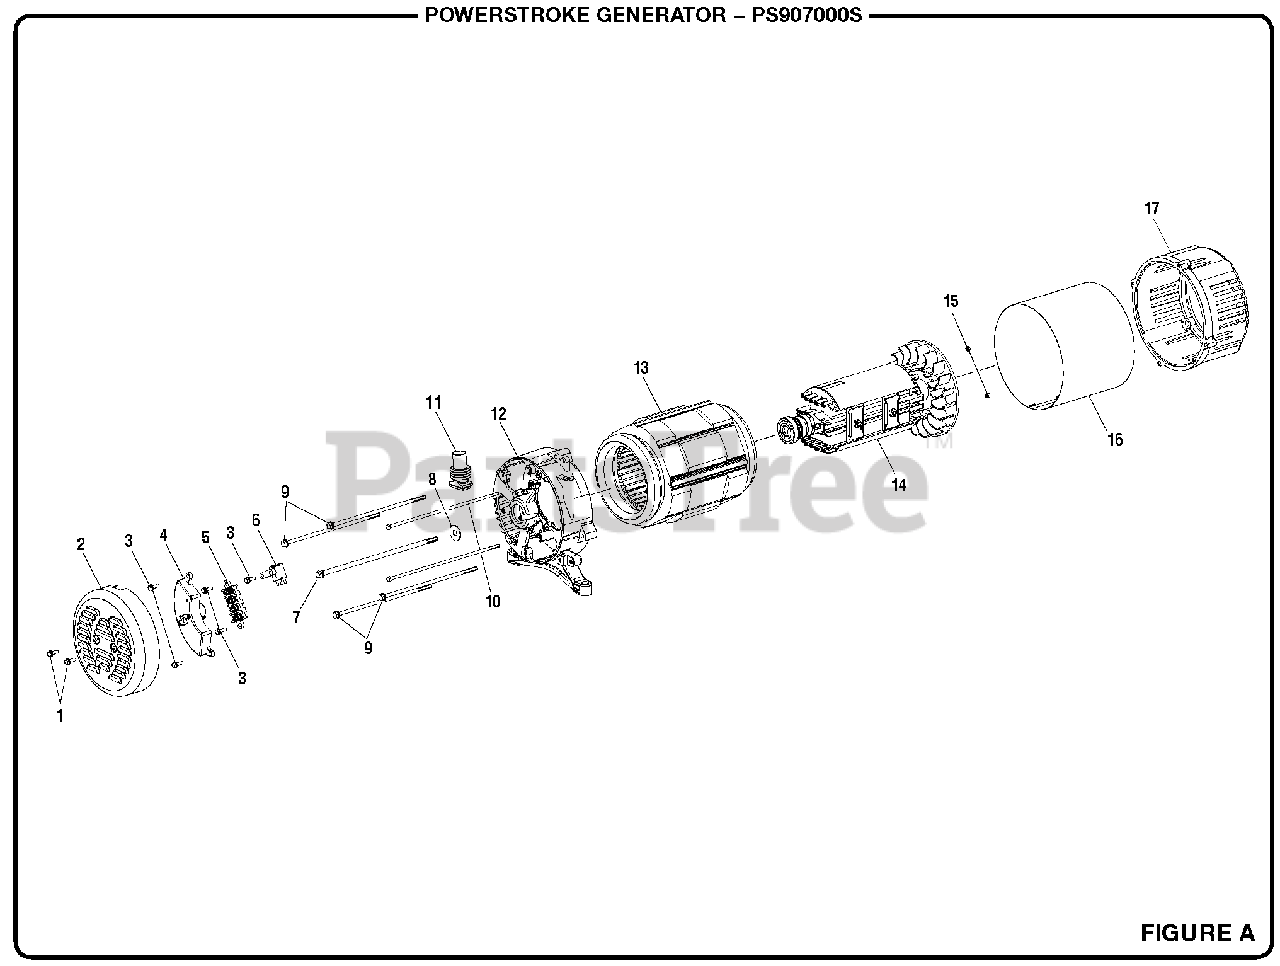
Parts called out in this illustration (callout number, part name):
1	Bolt (M5 x 12 mm, Hex Flange Hd.)
2	Brush Cover
3	Bolt (M5 x 16 mm, Hex Flange Hd.)
4	Automatic Voltage Regulator
5	Terminal Block
6	Brush Assembly
7	Rotor Bolt (5/16-24 x 260 mm, Hex Flange Hd.)
8	Washer (ID10.5 x OD25 x 2t)
9	Stator Bolt (M6 x 216 mm, Hex Flange Hd.)
10	Bolt (M5 x 245 mm, Hex Hd.)
11	Rubber Boot
12	Bearing Housing
13	Stator Assembly
14	Rotor Assembly
15	Hex Nut (M5)
16	Generator Head Cover
17	Engine Adaptor
